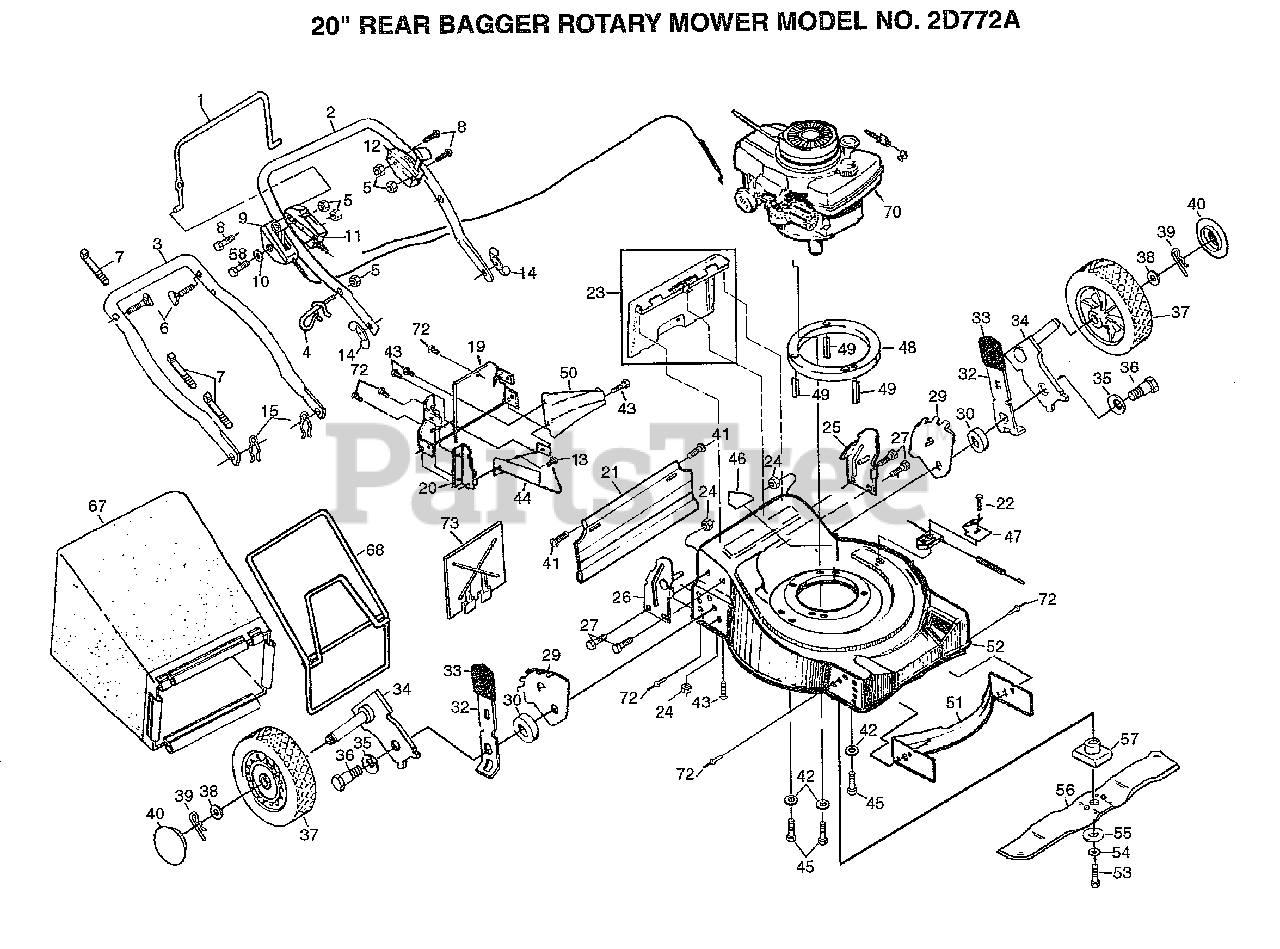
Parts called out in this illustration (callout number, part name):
1	CONTROL BAR
4	ROPE GUIDE
6	BOLT.HANDLE.LM
10	WASHER PM
11	ENGINE CONTROL
12	DRIVE CONTROL
13	SCREW PM
14	"NUT,WING PM"
15	HAIRPIN COTTER
22	"SCREW, HEX PM"
23	"KIT, REAR DOOR PM"
24	LOCKNUT PM
27	SCREW
32	SPRING SELECTOR
33	KNOB PM
34	AXLE ARM
35	"WASHER, BELLEVIL."
37	WHEEL&TIRE ASSY
38	WASHER
39	RETAINER CLIP PM
40	HUB CAP
41	HINGE SCREW
43	SCREW
44	DISCHARGE GUARD
45	SCREW
46	DECAL HYT
47	BRKT DRV COV
48	ENGINE SPACER
50	REAR BAFFLE
53	SCREW
54	LOCKWASHER
55	"WASHER,HARDEN"
57	ADAPTOR.BLADE.LM
67	GRASS BAG
68	CATCHER FRAME
72	BLIND RIVET
73	MULCHER PLATE
